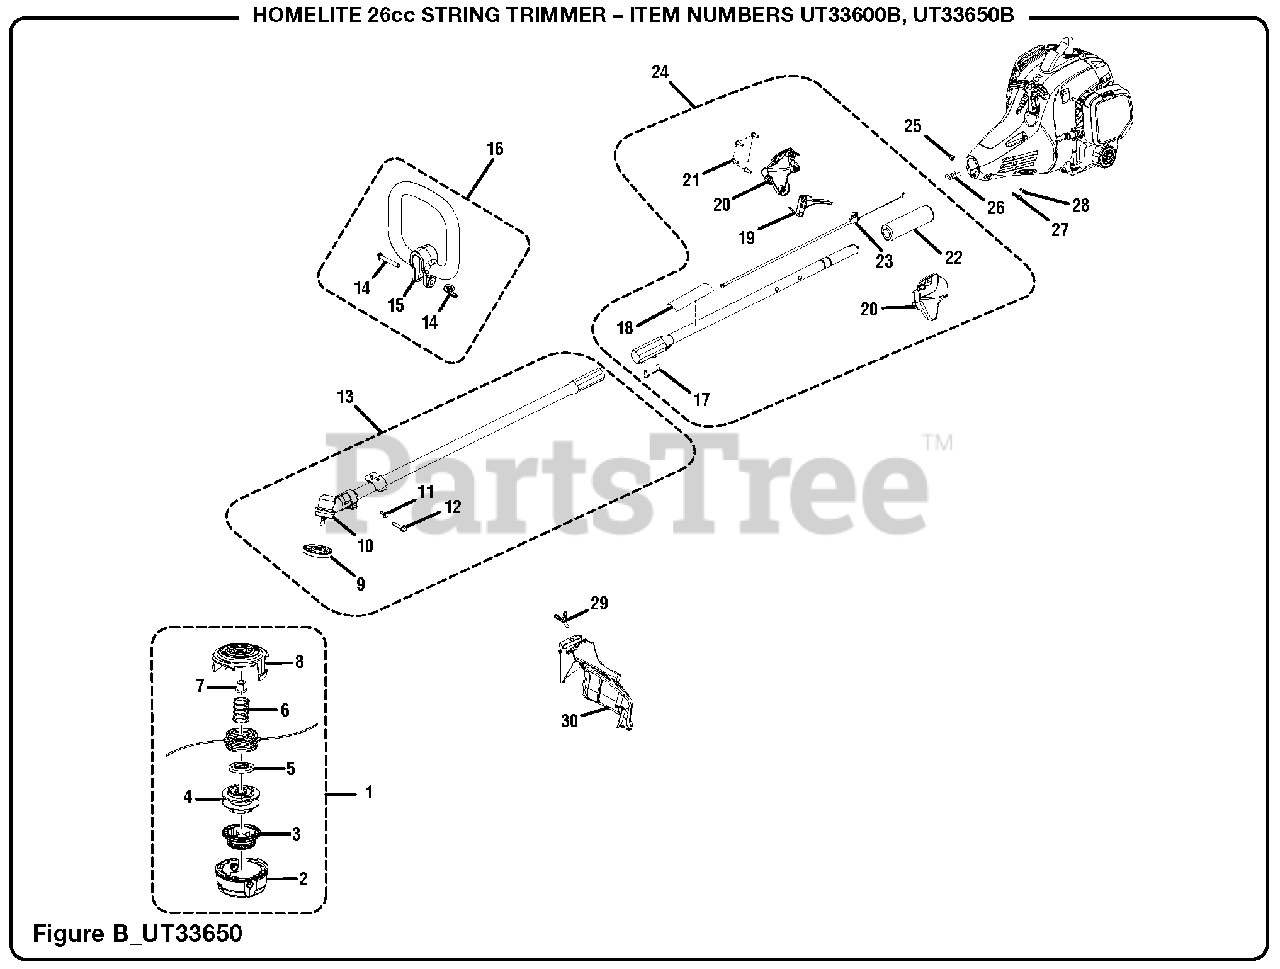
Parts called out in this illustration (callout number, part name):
1	Trimmer Head Assembly
2	Lower Housing
3	Bump Knob (Gray)
5	String Guide
6	Compression Spring
7	Hex Nut (M8, Left Hand Threads)
8	Upper Housing
9	Flanged Washer
10	Gear Head
11	Screw w/Washer (10-24 x 5/8 in.,Hex Hd. T.F.)
12	Screw (1/4-20 x 1-1/4 in., Hex Hd.)
13	Lower Boom Assembly
14	Fastener Kit
15	Front Handle
16	Front Handle Assembly
17	Set Screw (M5 x 10 mm, Hex Soc. Hd.)
18	Icon Warning Label
19	Throttle Trigger
20	Handle Assembly
21	Screw (M4 x 20 mm, T20 Torx Pan Hd. T.Fl.)
22	Foam Grip
23	Throttle Cable
24	Boom Assembly
25	Hex Nut (M6)
26	Compression Spring
27	Screw (M6 x 20 mm, T27 Torx Button Hd.)
28	Screw (M4 x 8 mm, T20 Torx Round Hd.)
29	Wing Nut (1/4-20)
30	Grass Deflector Assembly
